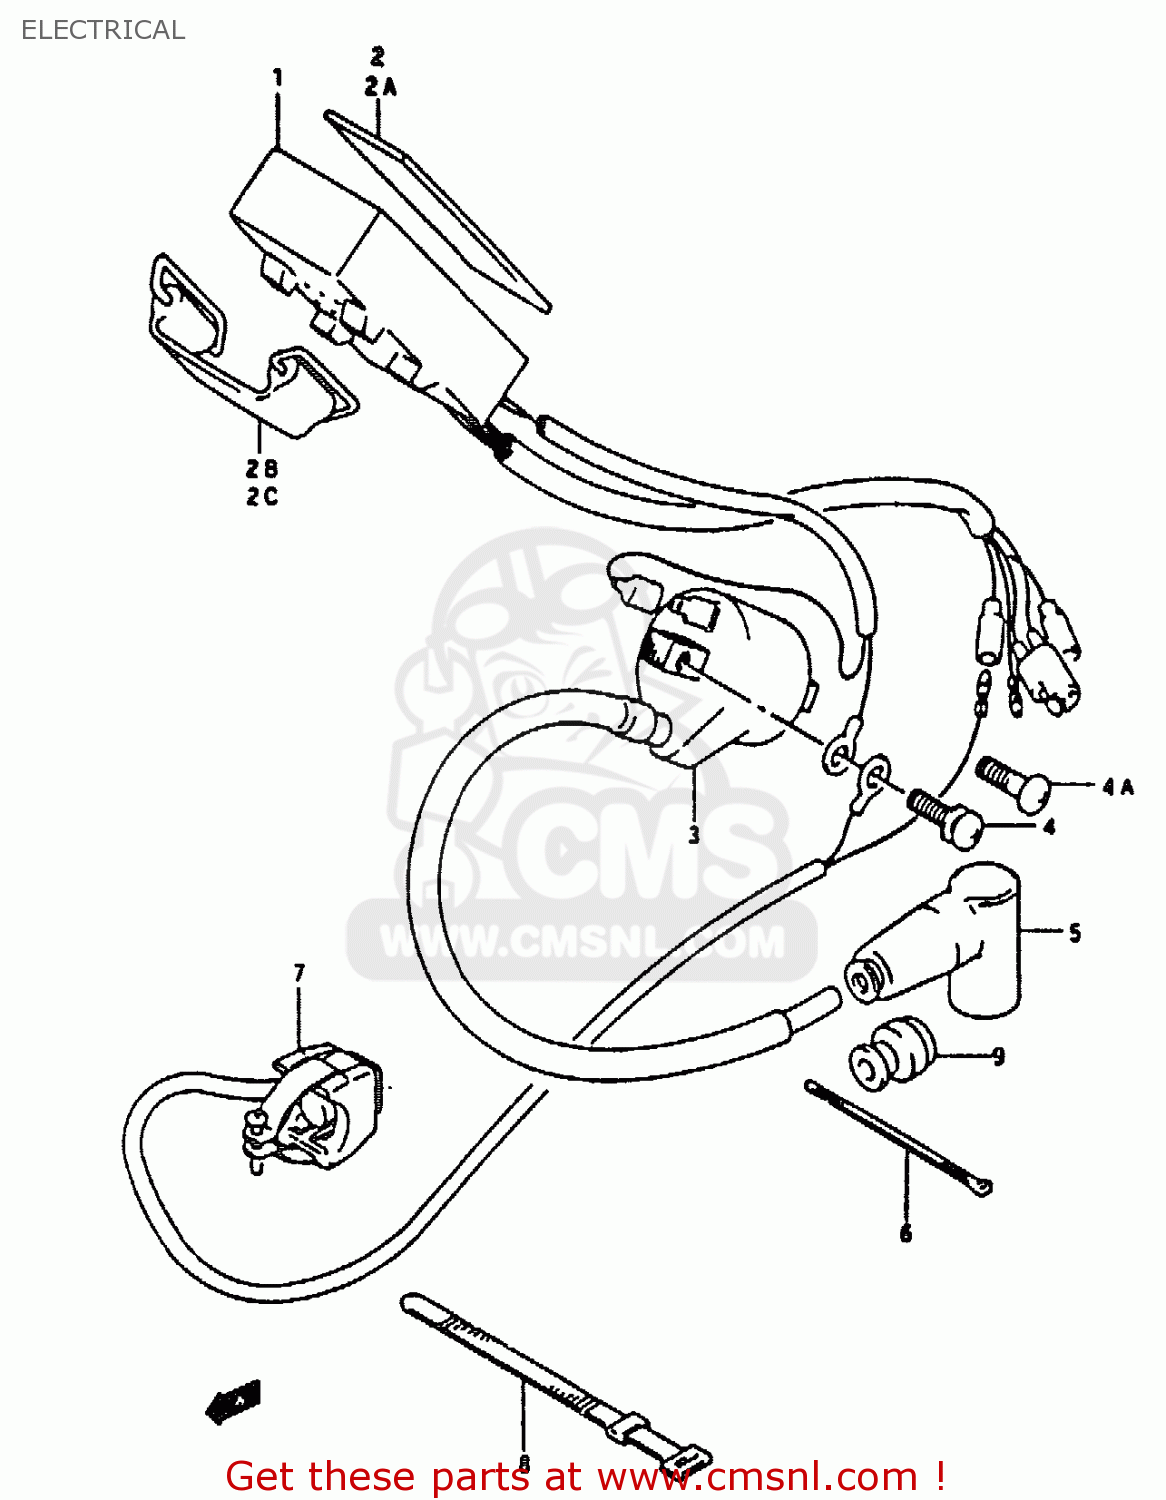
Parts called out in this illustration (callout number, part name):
1	CDI UNIT
2	PROTECTOR(170X95X3.0)
2A	PROTECTOR(170X95X3.0)
2B	BAND
2C	BAND(L:65)
3	COIL ASSEMBLY,IGNITION
4	SCREW
4A	SCREW, 6X20
5	CAP,SPARK PLUG
6	CLAMP
7	SWITCH ASSEMBLY
8	CLAMP(L:120)
9	SEAL,HIGH TENSION CORD
